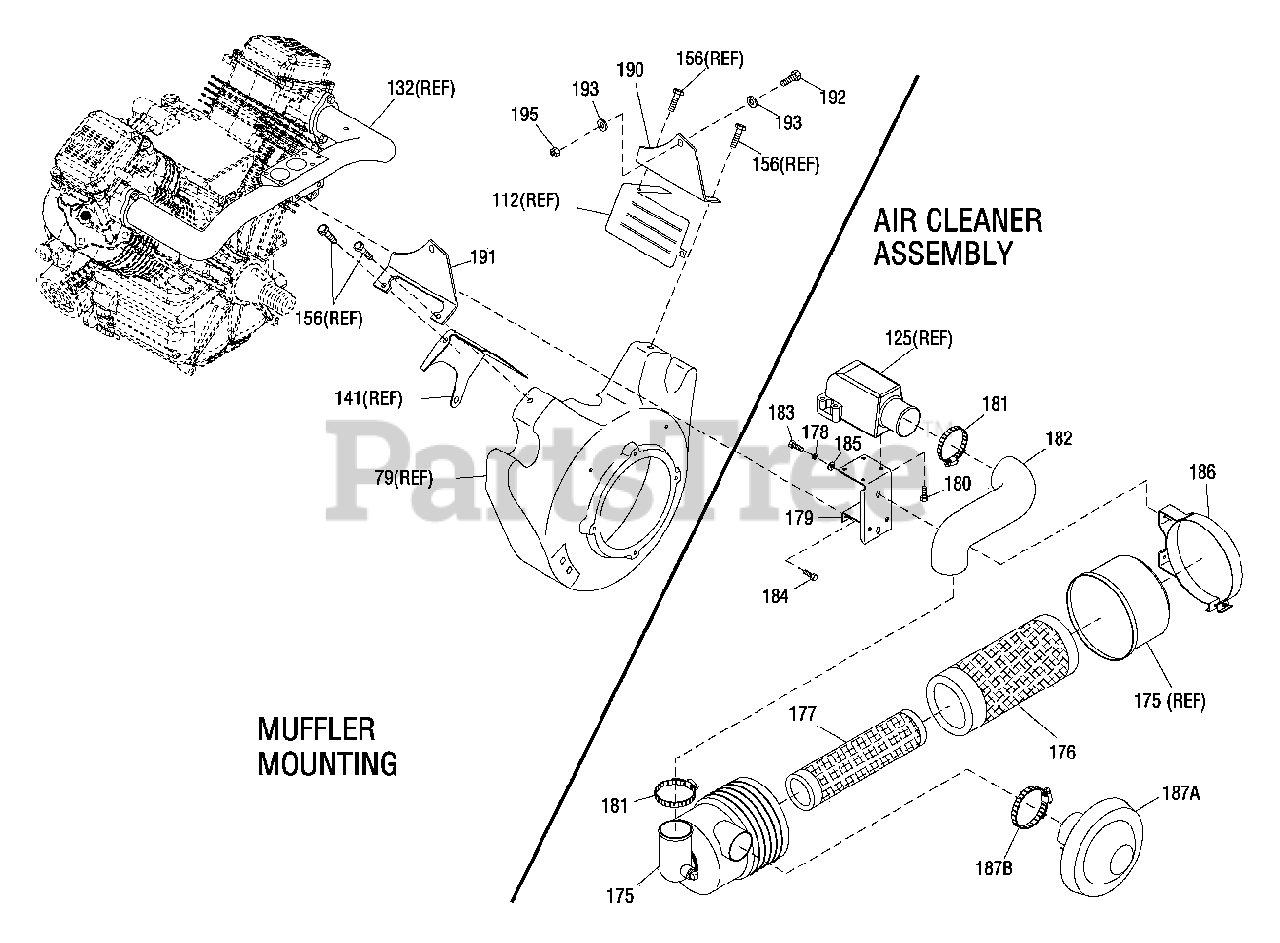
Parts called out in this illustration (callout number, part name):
79	HOUSING, BLOWER VERTICAL
92	PLATE, FAN
93	FAN, NYLON
112	WRAPPER, UPPER CYLINDER 1
125	ADAPTOR, CARB-AIRBOX, M6 BOSSES
132	MANIFOLD.INTAKE 2BBL CARB
141	WRAPPER, UPPER CYLINDER 2
156	SCREW, FHHC M6-1.0 x 12 W/M5 HEX
161	BRACKET, THROTTLE
175	CLEANER, AIR W/ SFTY FLT
176	FILTER, AIR PRIMARY
177	FILTER, AIR SAFETY (INNER)
178	WASHER LOCK M8-5/16
179	BRKT, AIR CLEANER SUPPORT
180	SCREW BHSC M6-1.0 x 12 SS
181	CLAMP HOSE #32 1.563-2.500
182	HOSE AIR CLEANER
183	SCREW HHC M8-1.25 x 16 G8.8
184	SCREW HHFC M6-1.0 x 10 G8.8
185	WASHER FLAT 5/16-M8 ZINC
186	ASSY, BAND MOUNT AIR CLEANER
187A	HOOD, INLET
187B	CLAMP, HOSE
